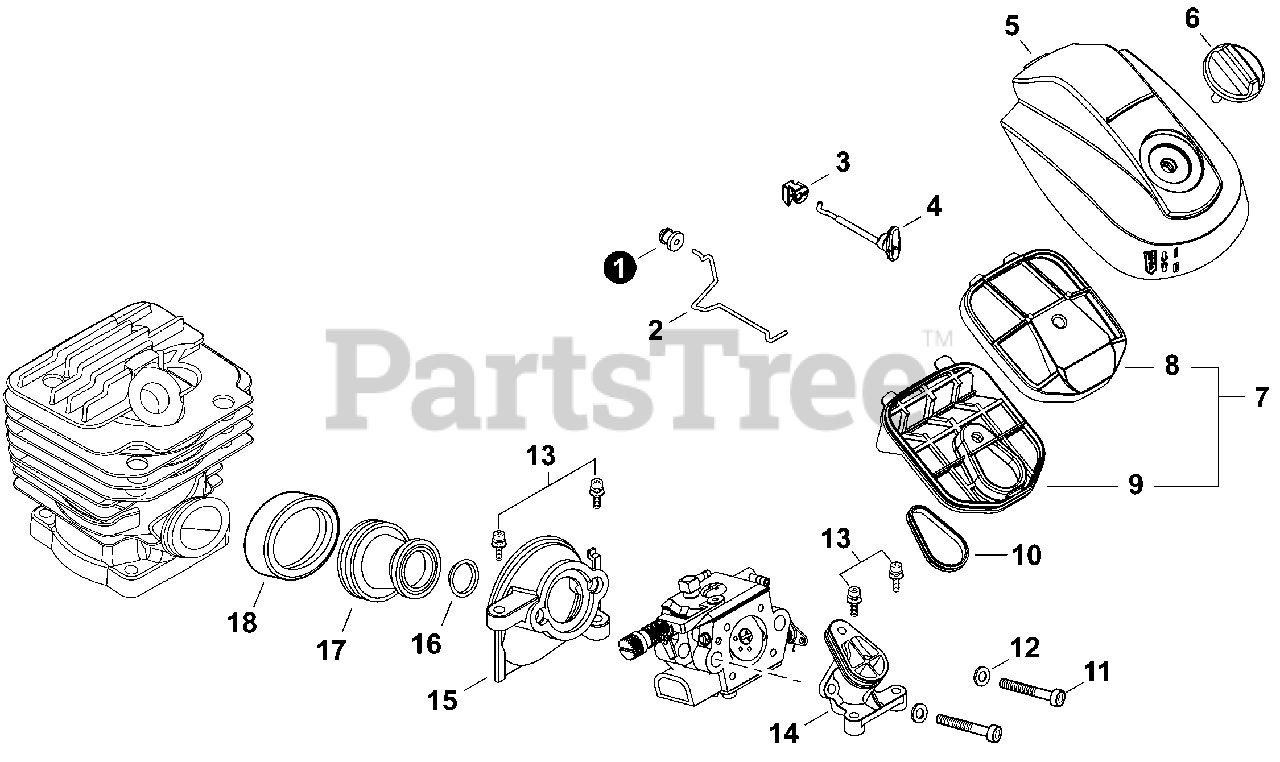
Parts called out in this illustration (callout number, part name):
1	GROMMET
2	ROD, THROTTLE
3	GROMMET, CHOKE
4	ROD, CHOKE
5	COVER, AIR FILTER
6	THUMBSCREW
7	AIR FILTER ASSY, FLOCKED
8	FILTER, FLOCKED UPPER AIR
9	FILTER, FLOCKED LOWER AIR
11	BOLT M5×48
12	WASHER, FLAT 5.5×10×0.8
13	BOLT M4×16
14	ADAPTOR, AIR FILTER
15	INSULATOR, INTAKE
16	COLLAR 16
17	BELLOWS, INTAKE
18	HOLDER, BELLOWS
